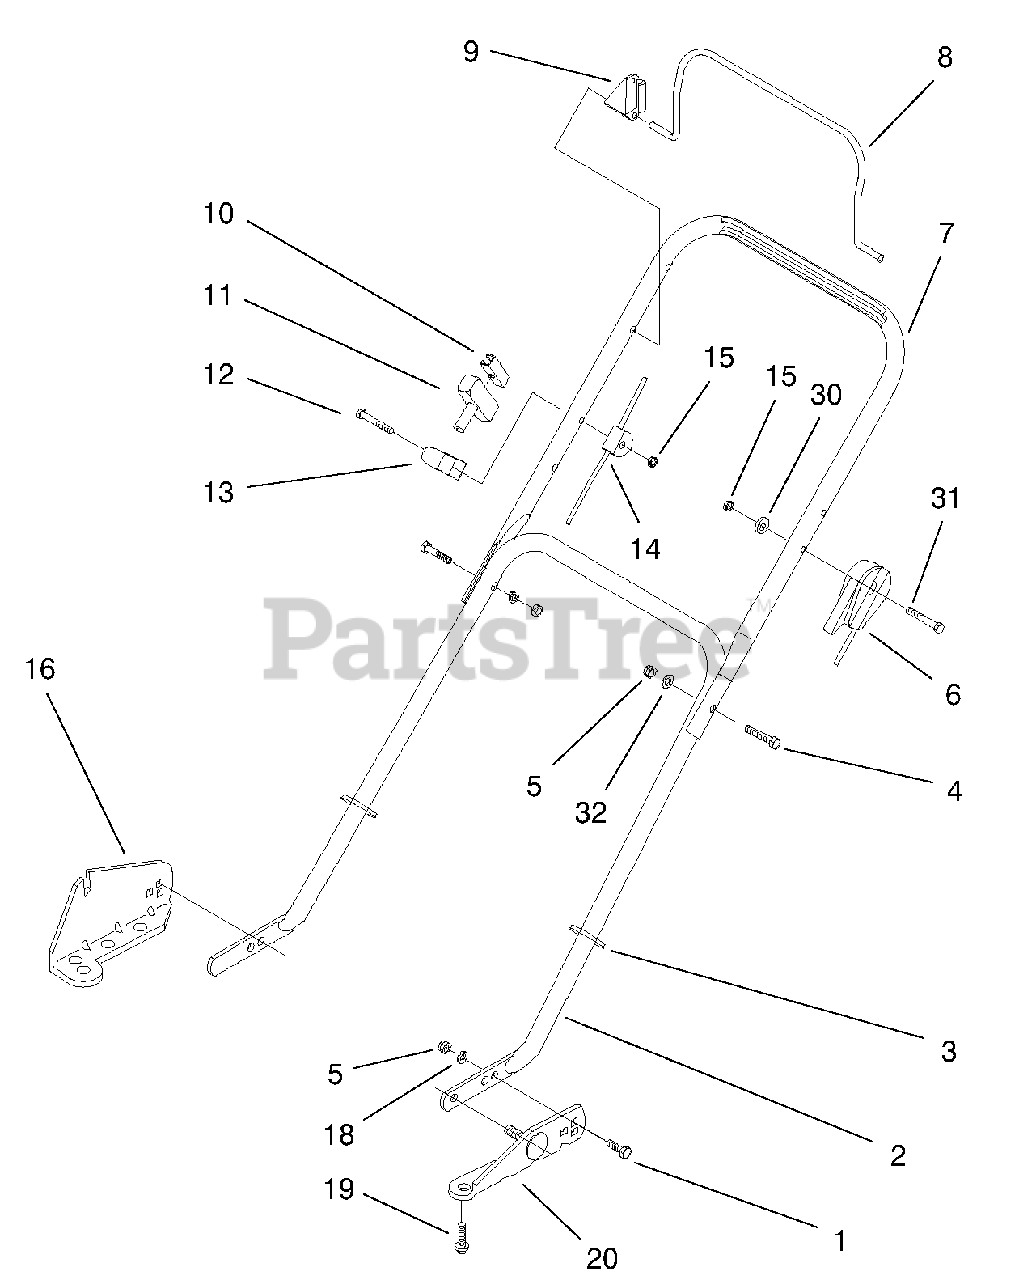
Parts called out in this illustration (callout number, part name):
1	Screw-CARR
2	Handle Section-Lower
3	Tie Strap
4	Screw-HH
5	Nut-Lock,NI
6	Cable-Throttle
7	Handle-Upper
8	Bail Control Lever ASM
9	Stop-Pivot
10	Starter-Clip
11	Handle-Start
12	Screw-HH
13	Rope-Guide
14	Cable-Brake
15	Nut-Lock NI
16	RH Bracket & Pin ASM
18	Washer-Lock/Sp
20	LH Bracket & Pin ASM
30	Washer
31	Screw-HH
32	Washer-Curved
